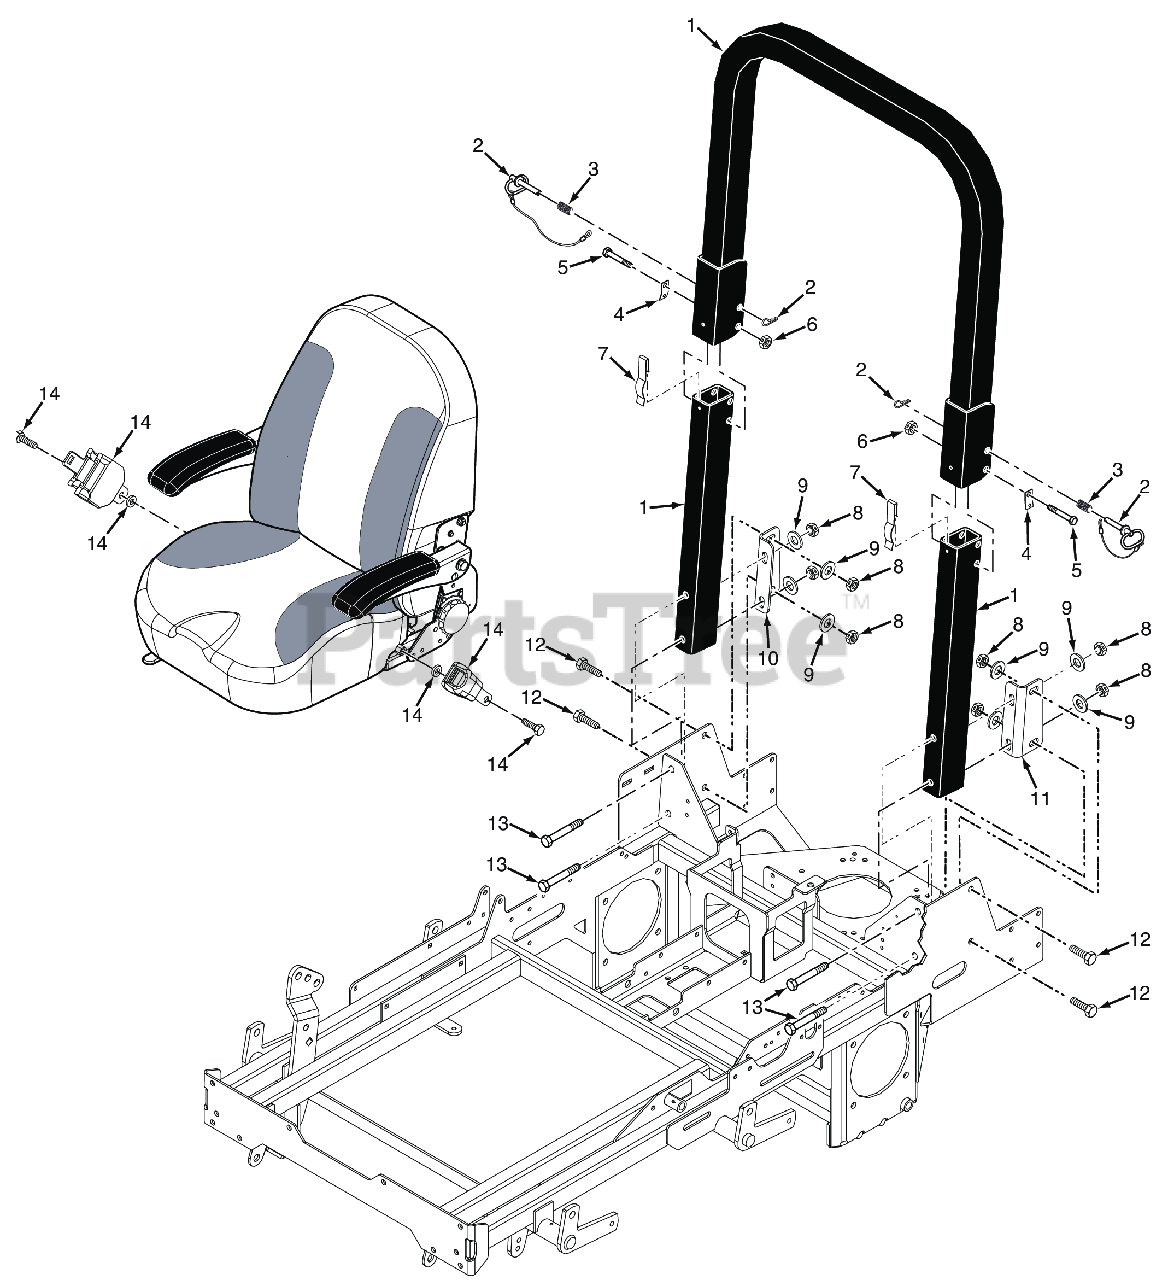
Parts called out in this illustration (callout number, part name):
1	ROPS, Foldable SCZ
2	Pin Assembly, ROPS Hinge
3	Spring, ROPS
4	Clip, ROPS
5	Bolt, Hex Head, 1/2-13 x 3-1/4"
6	HEX LOCKNUT, ELASTIC STOP, 1/2-13
7	Spring, ROPS Anti-Rattle
8	Locknut, Hex 1/2-13 Center Lock
9	Flat Washer, 1/2 (.562 x 1.375 x .109)
10	ROPS Mount, RH Rear
11	ROPS Mount, LH Rear
12	Bolt, Hex Head 1/2-13 x 1-1/4"
13	Bolt, Hex Head 1/2-13 x 4-1/4"
14	Seat Belt Kit, Retractable - SCZ
